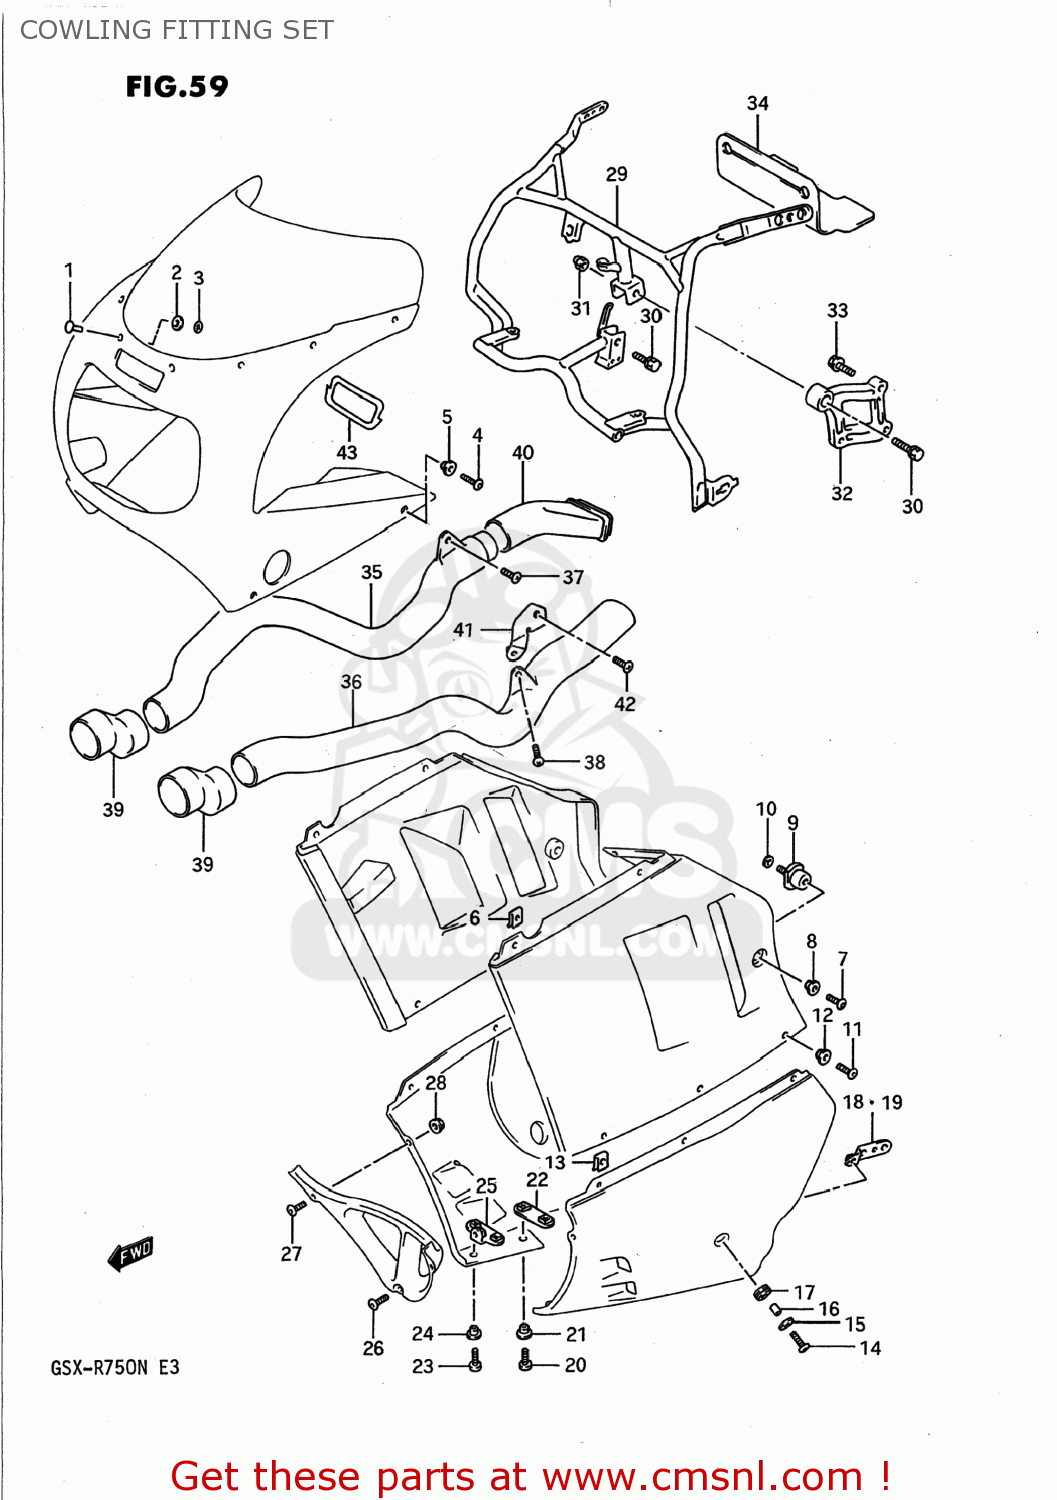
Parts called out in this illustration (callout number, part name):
1	PIN,WINDSCREEN
2	CUSHION
3	NUT
4	SCREW(5X18)
5	WASHER(5.2X14X1.5)
6	NUT,HEADLAMP HOUSING,UPPER
7	SCREW(6X12)
8	WASHER(6.3X16X1.5)
9	CUSHION,COWLING
10	WASHER,LOCK
11	SCREW(5X18)
12	WASHER(5.2X14X1.5)
13	NUT,HEADLAMP HOUSING,UPPER
14	SCREW(6X20)
15	WASHER(6.5X18X1)
16	SPACER
17	CUSHION
18	BRACE,COWLING LWR,R
19	BRACE,COWLING LWR,L
20	SCREW(6X16)
21	WASHER(6.3X16X1.5)
22	BRACE,COWLING LWR COVER RR
23	SCREW(6X16)
24	WASHER(6.3X16X1.5)
25	BRACE,COWLING LWR COVER
26	SCREW(6X16)
27	SCREW(5X14)
28	NUT
29	BRACE,COWLING
30	BOLT, BRACE (8X30)
31	NUT ,8MM
32	BRACE,COWLING CTR
33	BOLT, BRACE CENTER (8X40)
34	SHEET,COWLING HEAT GUARD
35	PIPE,AIR INTAKE,FRONT
36	PIPE,AIR INTAKE FR,L
37	SCREW
38	SCREW 6X12
39	JOINT,AIR INTAKE
40	PIPE,AIR INTAKE RR,R
41	PLATE,AIR INTAKE,LEFT
42	BOLT
43	CUSHION,FR POSITION LAMP
